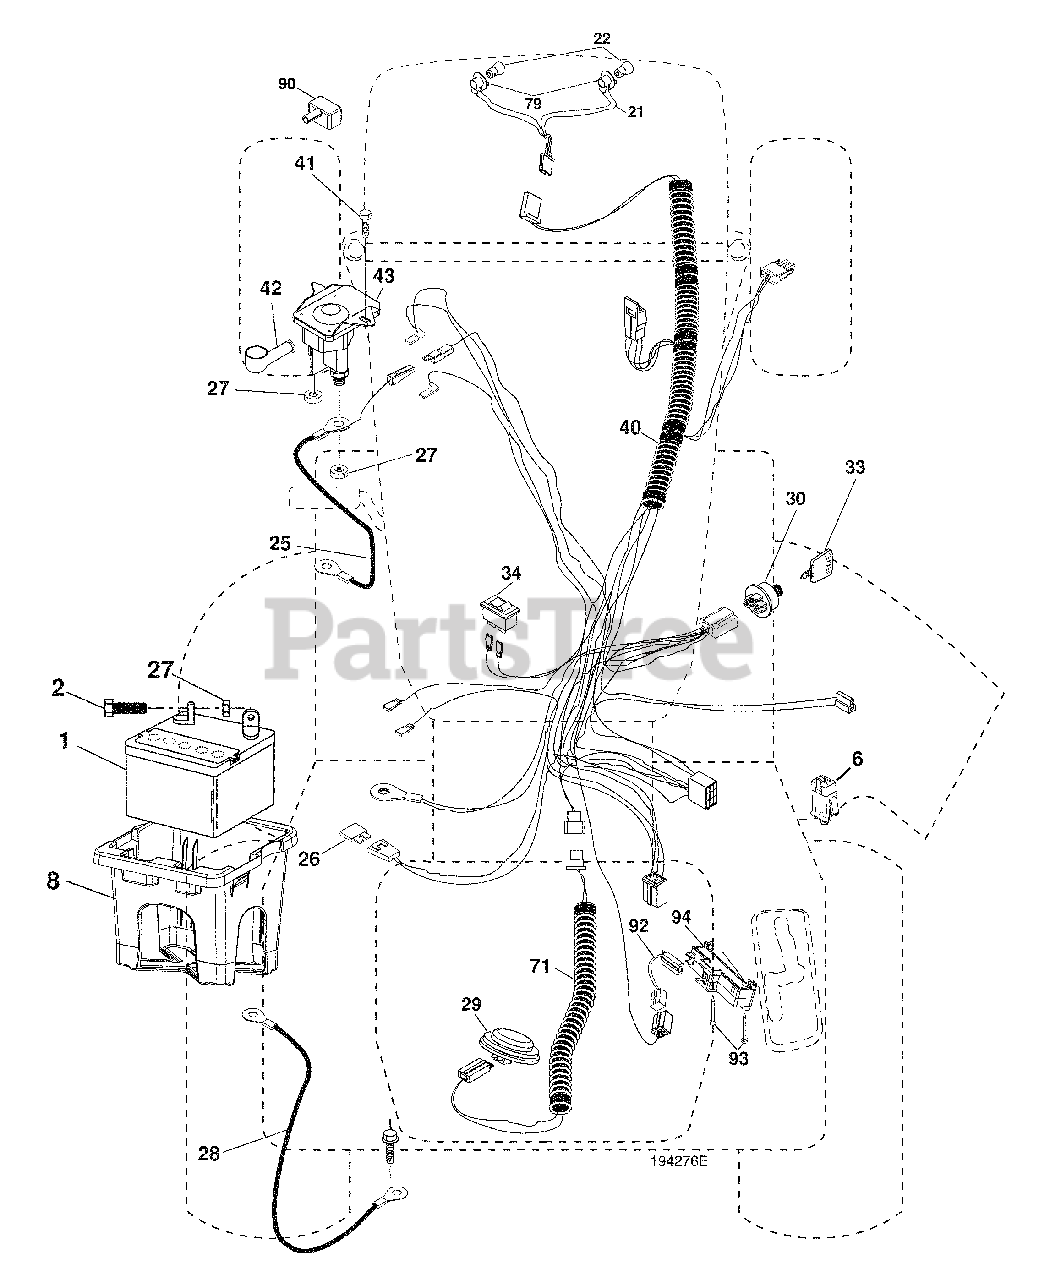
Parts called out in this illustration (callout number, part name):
1	Battery
2	Bolt Hex Head 1/4-20 x 3/4
8	Box Battery
16	Switch Interlock Push-In
21	Harness Socket Light W/4152J
22	Bulb Light
25	Cable Starter
27	Nut Keps Hex 1/4-20 unc
28	Cable, Ground
29	Switch, Seat
30	Switch, Ign
33	Key, Ignition
34	Switch Light / Reset
40	Harness Ign. Dash
41	Screw Thd Cut 1/4-20 x 1/2
42	Cover, Terminal
43	Solenoid
55	Screw Thdrol 5/16-18 x 1/2 TYTT
71	Harness Ign.
79	Socket Asm. Bulb Twistlock
90	Cover Terminal
92	Harness Pigtail Reverse Switch
93	Screw Plastite 10-14 x 2.0
94	Module Reverse ROS
